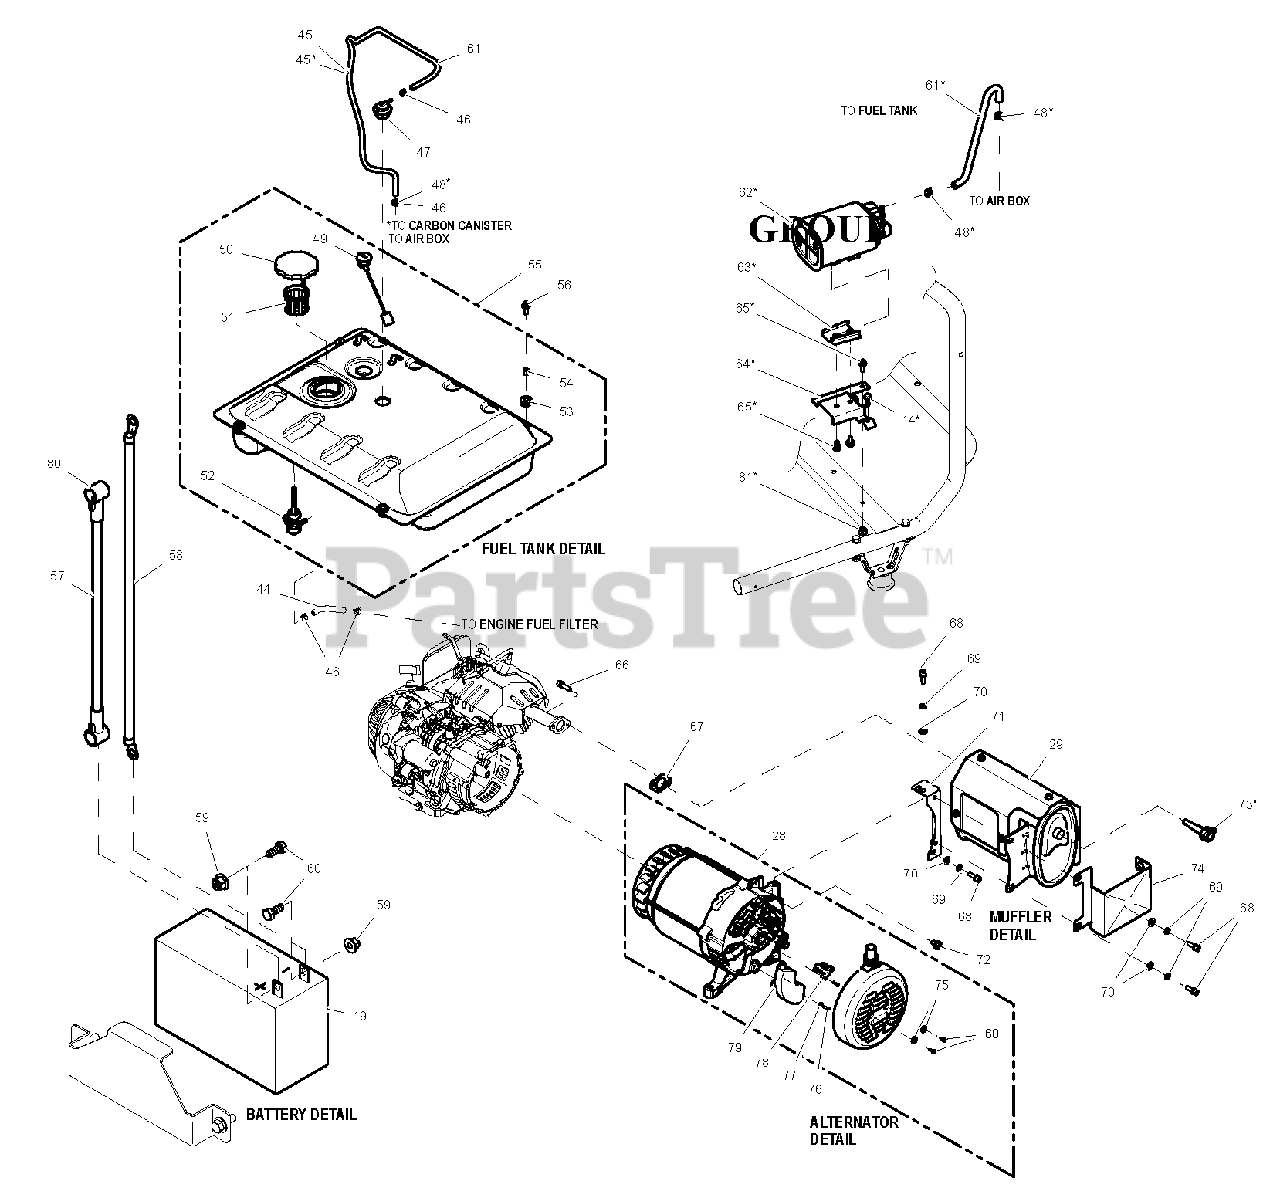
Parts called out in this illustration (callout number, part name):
44	FUEL HOSE 4 ID X 8.5OD X 55MM
45	HOSE FORMED ROV-AIRBOX 420CC
45	HOSE FORMED ROV-CANISTER 420cc
46	CLAMP HOSE BAND .41
47	ASSEMBLY ROV
48	CLAMP HOSE BAND .50
49	FUEL GAUGE 150 MM LONG ARM
50	ASSY GAS CAP SEALED - BLACK
51	STRAINER, FUEL CAP
52	VALVE, FUEL SHUT OFF
53	RUBBER MOUNT,10.3 ID X 11 HGT
54	ANTI-CRUSH 10.8OD 9ID 10LG
55	FUEL TANK ASSY 8 GAL XT
56	SCREW HHFC M8-1.25 X 20 W/M10
57	WIRE ASSY 8GA 11" RED
58	WIRE ASSY 8GA 17" BLACK
59	NUT FLANGE M5-0.8 NYLOCK
60	SCREW HHC M5-0.8 X 12 C8.8
61	HOSE FORMED ROV-CANISTER 420CC
62	CARBON CANISTER
63	CARBON CANISTER MOUNT XT
64	CARB CAN CRADLE BRACKET XT
65	SCREW HHFC M6-1.0 X 12 G8.8
66	SCREW SHC M8-1.25 X 30LG SEMS
67	GASKET, EXHAUST, 389CC
68	SCREW SHC M8-1.25X25 G8.8 SEMS
69	WASHER LOCK M8-5/16
70	WASHER FLAT 5/16-M8 ZINC
71	BRACKET, MUFFLER 389CC
72	SCREW HHFCS M6-1 X 12 G8.8
73	SPARK ARRESTOR ASSY USFS
74	HEAT SHIELD
75	WASHER LOCK M5
76	SCREW HHC M5-0.8 X 16 G8.8
77	WASHER FLAT M5
78	ASSEMBLY,BRUSH
79	AVR 5.5-7.5KW VISION ALT
80	BOOT, VINYL STARTER-SOLENOID
81	NUT HEX LOCK M6-1 NY INS
